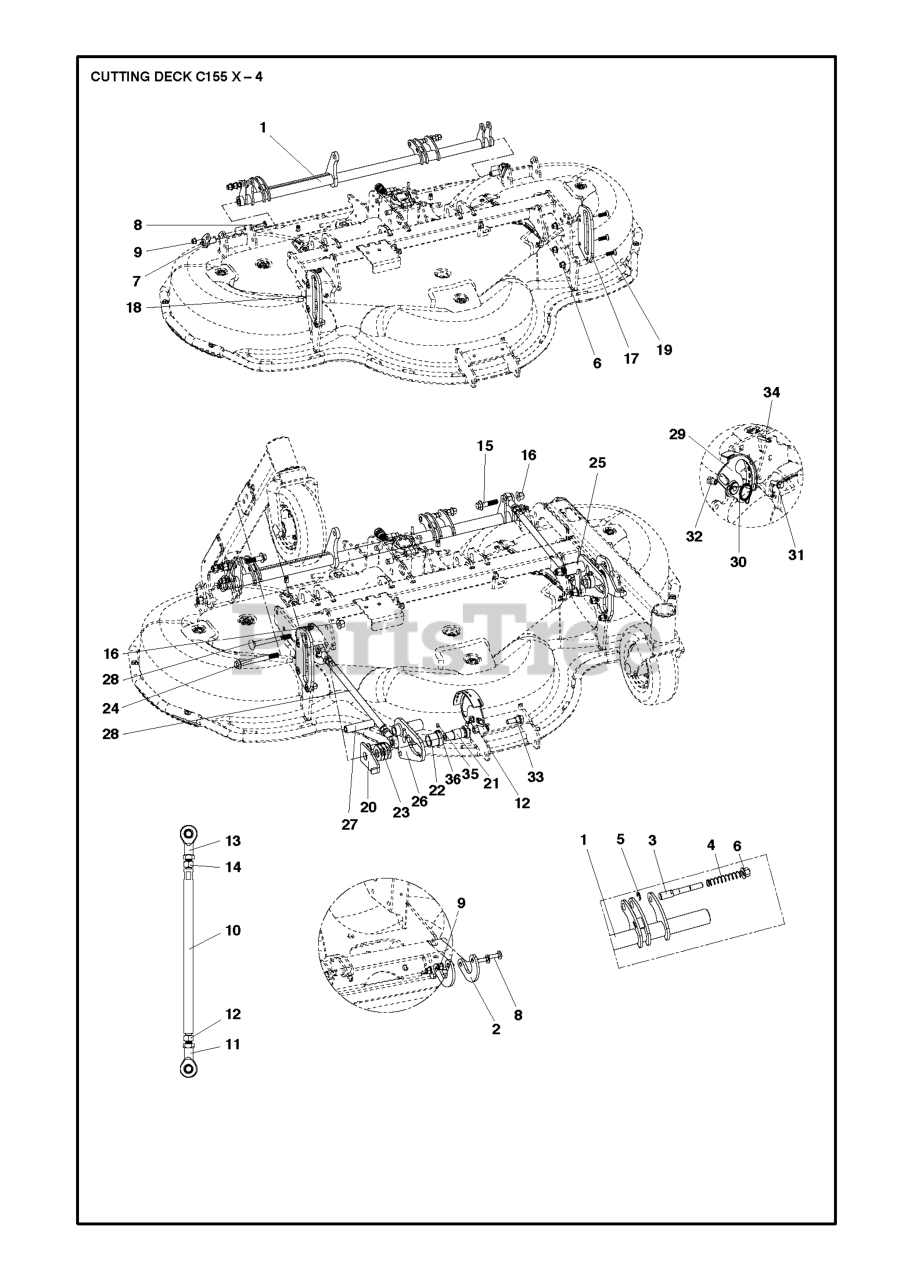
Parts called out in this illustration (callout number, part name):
9	NUT FLANGE
31	BOLT
35	GREASE NIPPLE
36	WASHER - M6
